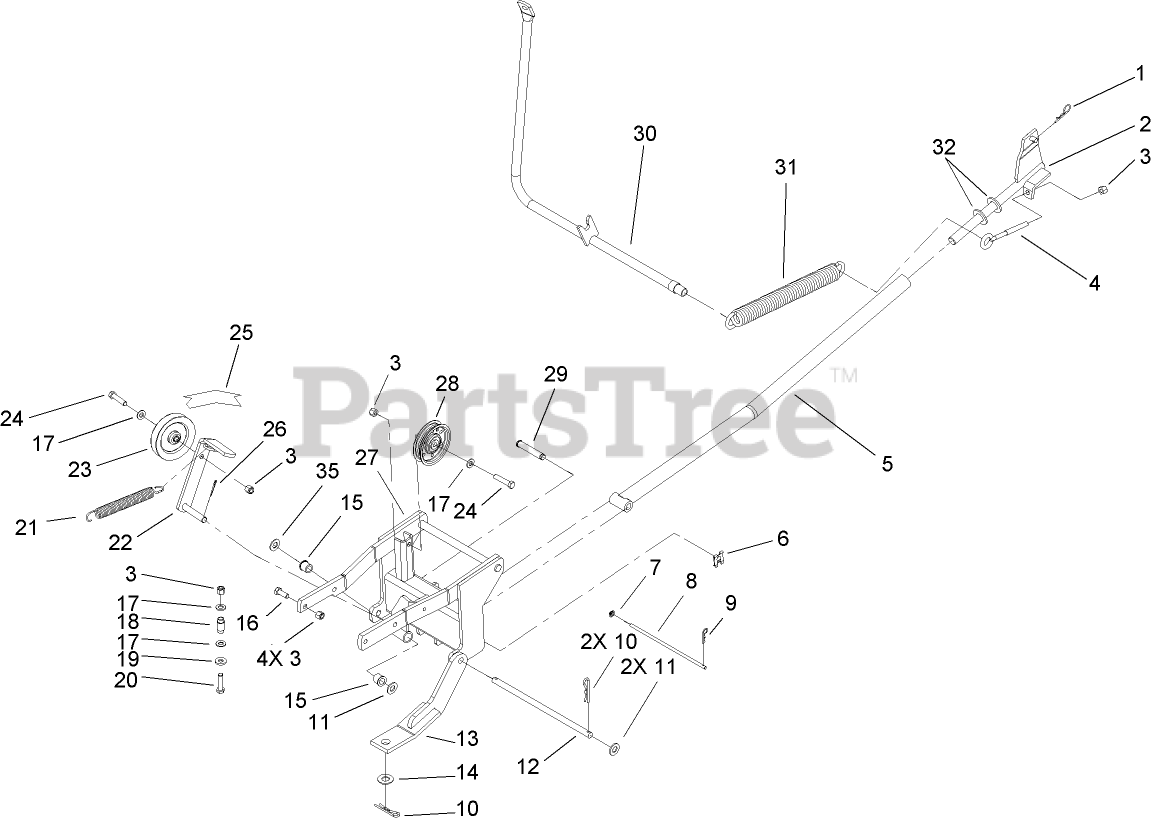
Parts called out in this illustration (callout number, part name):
1	PIN-HAIR
2	ROD-LIFT ASM
3	NUT-LOCK, NI
4	EYEBOLT
6	CLIP-PIN
7	NUT-SPEED
8	ROD-STOP
9	PIN-HAIR
10	PIN-COTTER, HAIR
11	WASHER-FLAT
12	ROD-SUPPORT
13	LINK ASM
14	WASHER-FLAT
15	BUSHING
16	SCREW-HH
17	WASHER-FLAT
18	SPACER-BEARING
19	WASHER-SPACER
20	SCREW-HH
21	SPRING-EXTENSION
22	IDLER ARM ASM
23	PULLEY-V, IDLER
24	SCREW-HH
25	V-BELT, JACKSHAFT
26	PIN-COTTER
27	FRAME ASM
29	PIN-CLEVIS
30	SUPPORT ROD ASM
31	SPRING-EXTENSION
32	WASHER-FLAT
35	WASHER
